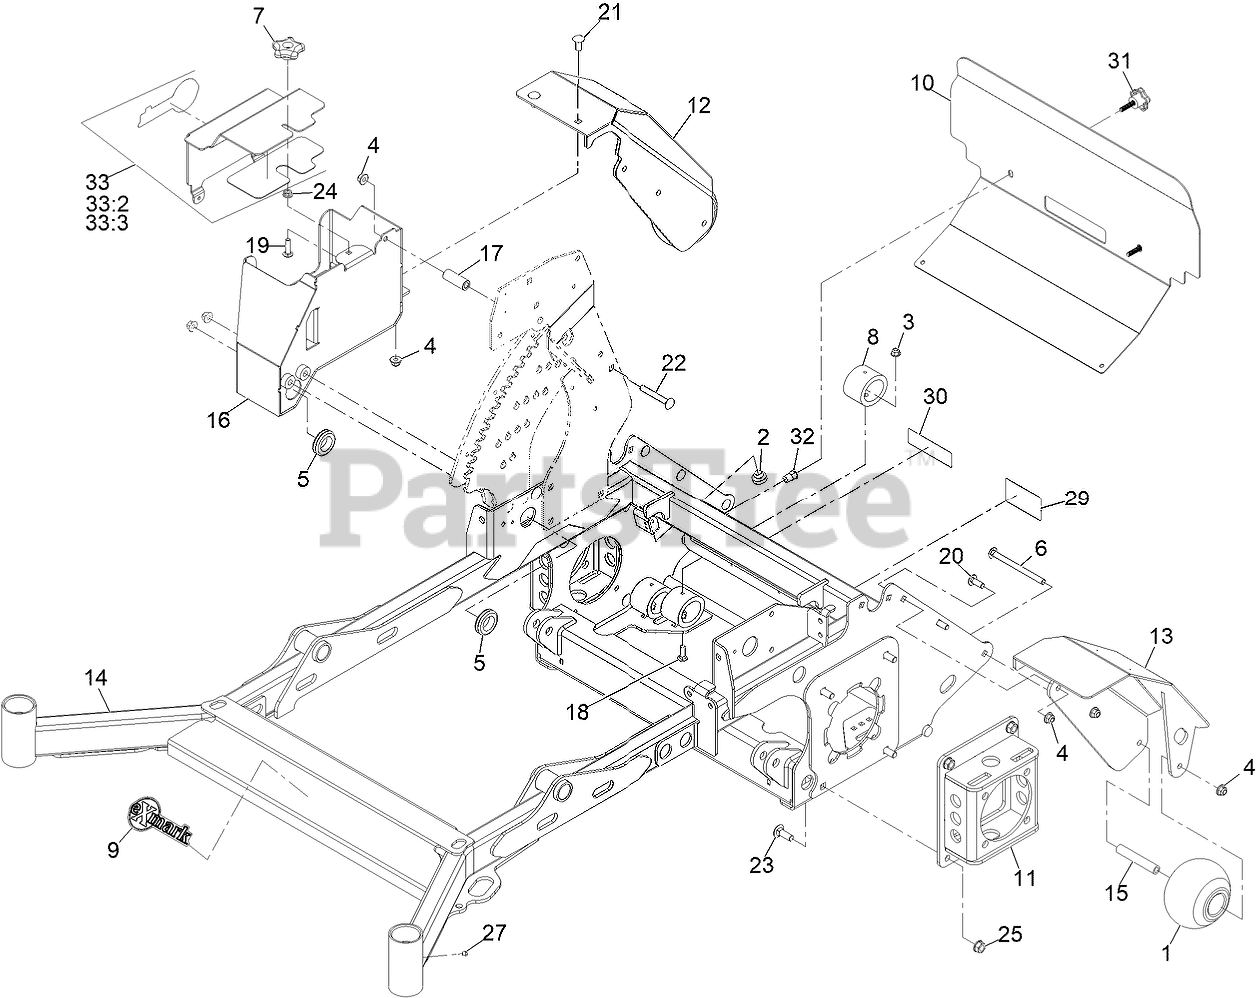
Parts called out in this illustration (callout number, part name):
1	ROLLER-SCALP, ANTI
2	BUMPER-RUBBER
3	NUT-HF, NI
4	NUT-HF, NI
5	GROMMET
6	BOLT-CARR
7	KNOB-HANDLE
8	BUMPER-ISOLATOR
9	DECAL-EXMARK LOGO
10	GUARD-REAR FOOT
11	WLD-MTR MOUNT 60
12	FENDER- WHEEL RH
13	FENDER- WHEEL LH
14	Mainframe ASM - 60
15	SPACER- ROLLER
16	WELD-BATTERY BOX
17	SPACER- ROLLER
18	BOLT-CARR
19	SCREW-CARR
20	SCREW-CARR
21	SCREW-CARR
22	SCREW-CARR
23	BOLT-CARR
29	DECAL-DRIVE RELEASE
30	DECAL-COVER, MISSING
32	NUT-CLINCH
33	ASM-LID BATTERY W/PAD
33:2	PAD-BATTERY BOX LID
33:3	DECAL-EXMARK LOGO
